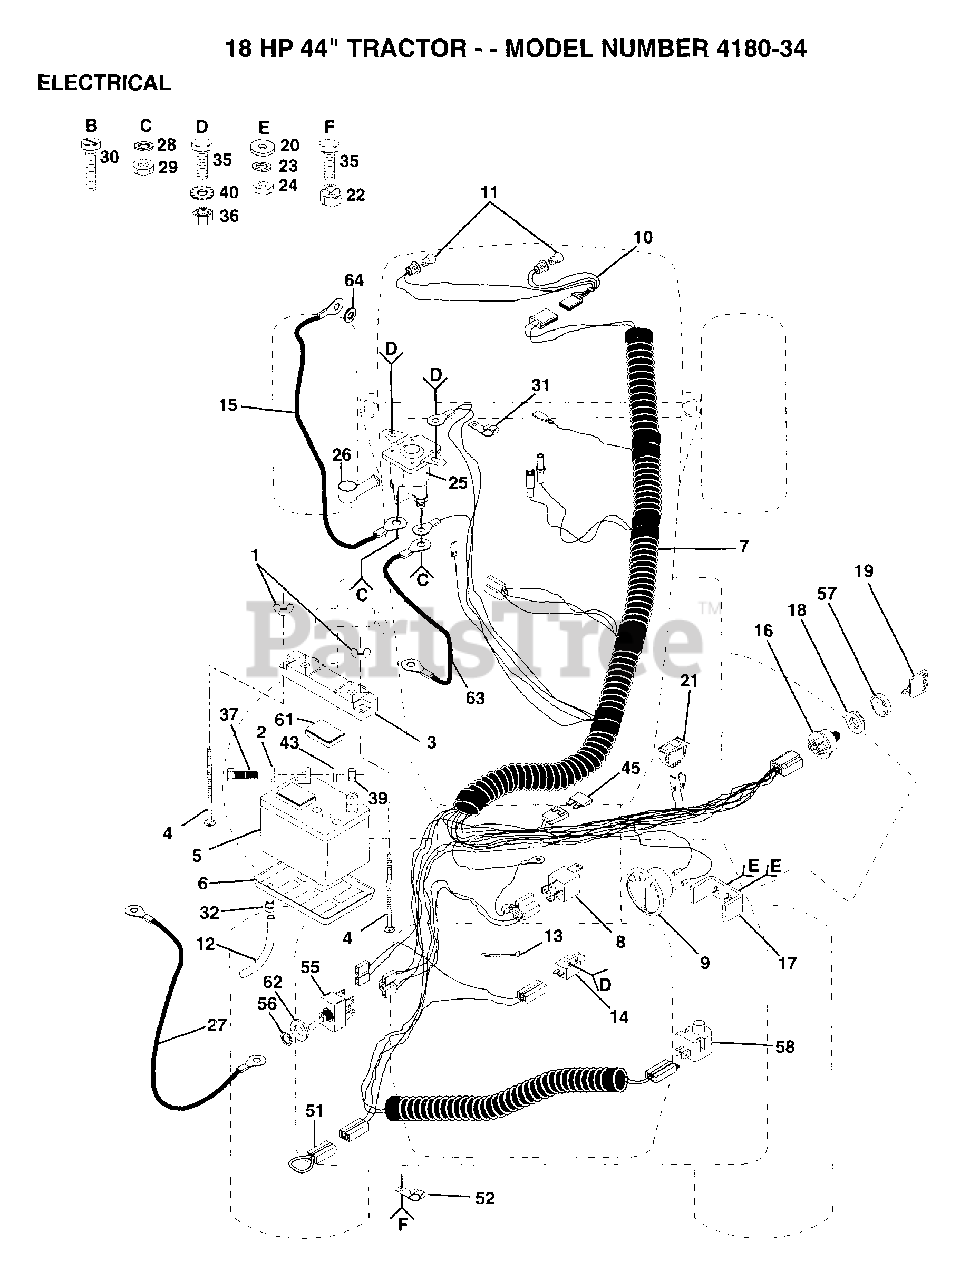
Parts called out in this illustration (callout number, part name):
2	WASHER
4	BOLT
6	"TRAY T, BATTERY"
7	HARNESS.IGN
8	RELAY ASSY T
9	AMMETER T
12	"DRAIN TU T, BATT"
13	WIRE TIE
14	SWITCH-INTER. GT
15	CABLE-BATTERY T
18	NUT IGNITION
19	KEY
20	WASHER
21	SWITCH LT
27	CABLE T
29	NUT
30	SCREW
31	CLIP T
32	HOSE CLAMP T
35	BOLT
36	NUT
37	BOLT LT
43	LOCKWASHER
45	FUSE HYT
52	CLIPT
56	HEX NUT T
58	SWITCH SEAT
61	"CAP,BATTERY "
62	WASHER
63	"CABLE T, BATTERY"
64	LOCKWASHER
